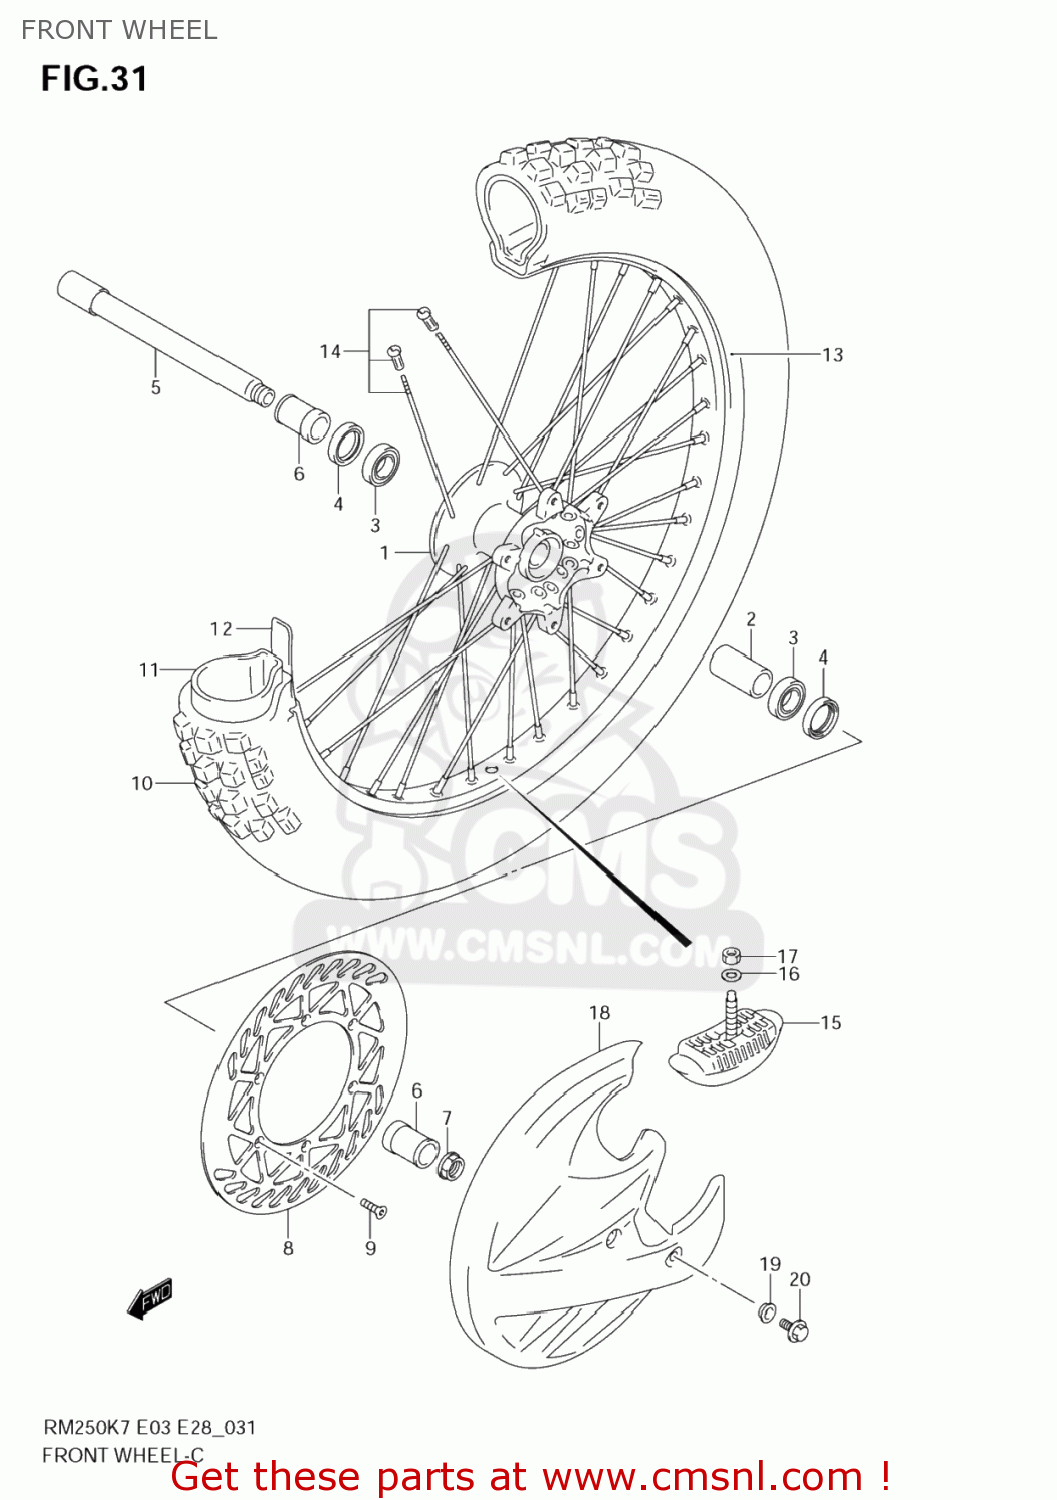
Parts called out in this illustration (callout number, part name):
1	HUB,FR WHEEL
2	SPACER,FR HUB BEARING
3	BEARING
4	SEAL,OIL(28X37X7)
5	AXLE,FR
6	SPACER,FR AXLE
7	NUT
8	DISC,FR BRAKE
9	SCREW(6X18)
10	TIRE,FR(80/100 21)
11	TUBE
12	PROTECTOR,WHEEL,INNER
13	RIM,FR WHEEL(1.60X21)
14	SPOKE SET,FR WHEEL
15	STOPPER,BEAD
16	WASHER
17	NUT
18	COVER,FR BRAKE DISC
19	WASHER
20	BOLT(6X12)
